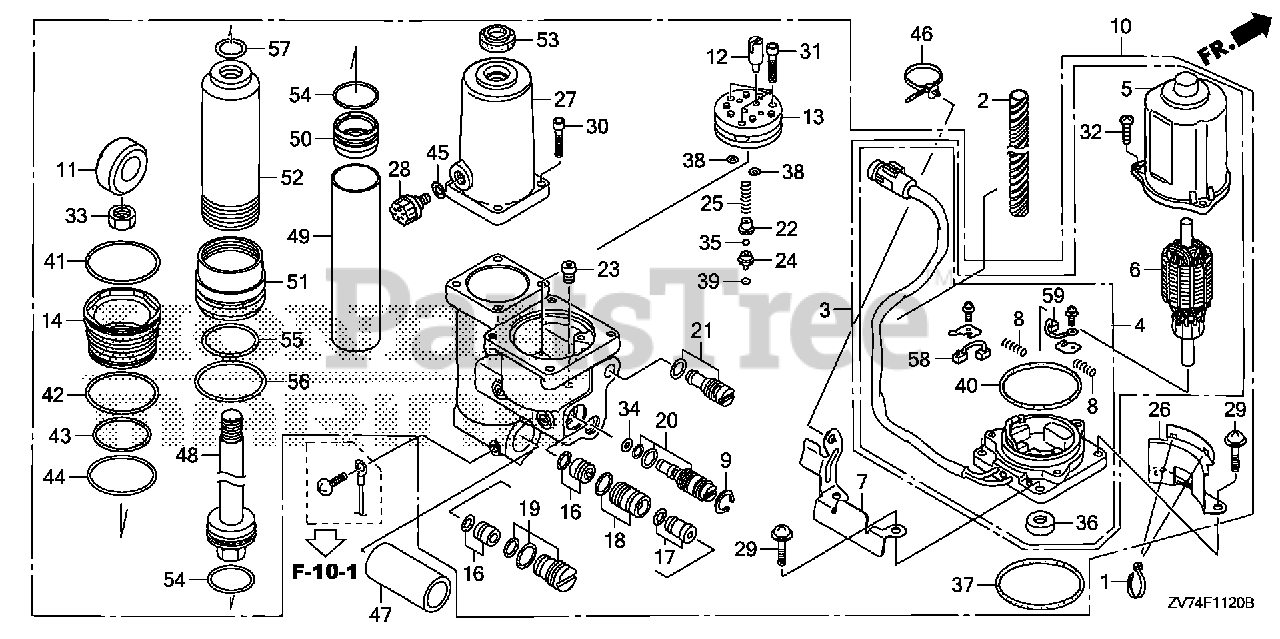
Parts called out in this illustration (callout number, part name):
1	BAND (BLACK 3.5X140)
2	TUBE, SPIRAL
3	MOTOR ASSY., POWER TILT
4	BRACKET ASSY.
7	CLAMP, WIRE
8	SPRING, MOTOR
9	CIRCLIP (INNER) (16)
10	TRIM-TILT ASSY., POWER
11	METAL, JOINT
12	JOINT, DRIVE
14	GUIDE, TUBE (OUTER)
20	VALVE, MANUAL
22	GUIDE, SPRING
23	VALVE, SET
24	SEAT B, VALVE
25	SPRING, VALVE
26	PLATE, SET
28	CAP, OIL TANK
29	SCREW-WASHER
30	BOLT, SOCKET (5X0.8)
32	SCREW, PAN (5X20)
33	NUT, JOINT METAL
34	WASHER, SEAL
35	BALL, STEEL
37	O-RING (1.8X69.6)
38	O-RING (1.5X6.5)
39	O-RING (1.5X3.5)
40	O-RING (2.0X55.5)
41	O-RING (2.0X52.5)
42	O-RING (2.0X49.5)
43	O-RING (2.4X41.2)
44	O-RING (2.0X45.5)
45	O-RING (1.8X10.8)
46	CLIP, HARNESS BAND (145MM) (BLACK)
47	COLLAR, DISTANCE
48	ROD, PISTON
50	PISTON, FREE
51	LOWER TILT CYLINDER
52	TUBE (OUTER)
53	SEAL, WATER
54	O-RING (2.0X28.5)
55	O-RING (2.0X34.5)
56	O-RING (3.5X41.7)
57	O-RING (2.4X15.8)
58	BREAKER ASSY.
59	BRUSH ASSY.
